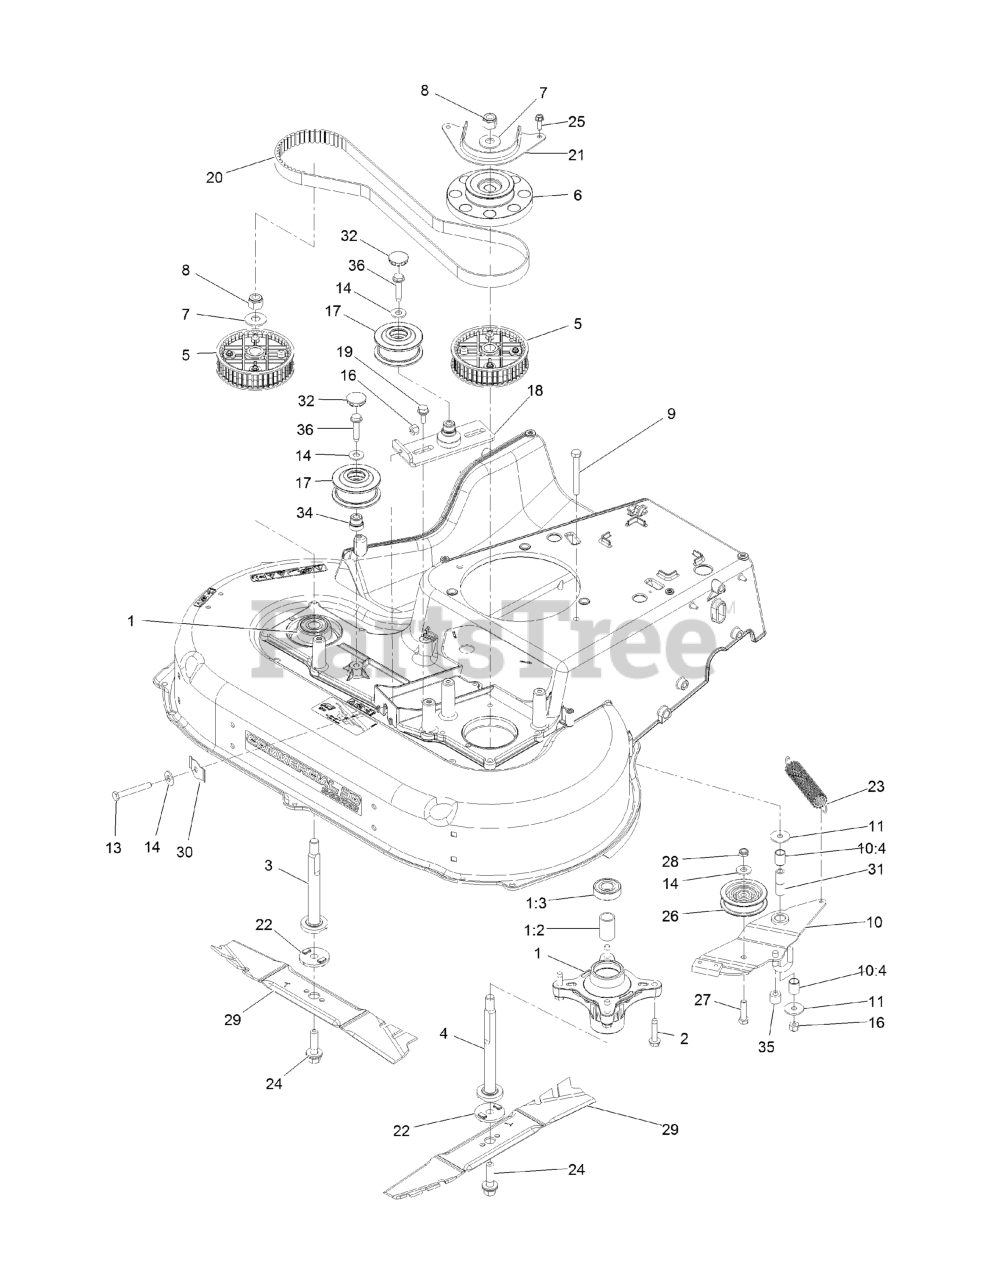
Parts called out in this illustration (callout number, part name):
1	SPINDLE ASM
1:3	BEARING-BALL
2	SCREW-THD ROLL, HWH
3	SHAFT-SPINDLE
4	SHAFT-SPINDLE
5	SPROCKET
6	PULLEY-BRAKE, SPINDLE
7	WASHER-SPRING
8	NUT-HEX
9	SCREW-HH
10	BRAKE ARM ASM
10:4	BUSHING-SLEEVE
11	WASHER-PIVOT
13	BOLT-TAP, HH
14	WASHER-FLAT
16	NUT-LOCK, NI
17	PULLEYS AND IDLER KIT
18	BRACKET-IDLER
19	SCREW-SHOULDER,HWH
20	BELT-SYNCHRONOUS
21	GUIDE-BELT, SPINDLE
22	ADAPTER-BLADE
23	SPRING-EXTENSION, BRAKE
24	BOLT-BLADE
25	SCREW-HWHTF
26	PULLEY-IDLER
27	SCREW-HH
28	NUT-LOCK, NI
29	BLADE-ROTARY
30	SPRING-FLAT
31	SPACER-BRAKE
32	PLUG-BUTTON
34	ADAPTER-BORE
35	HOSE-COOLANT
